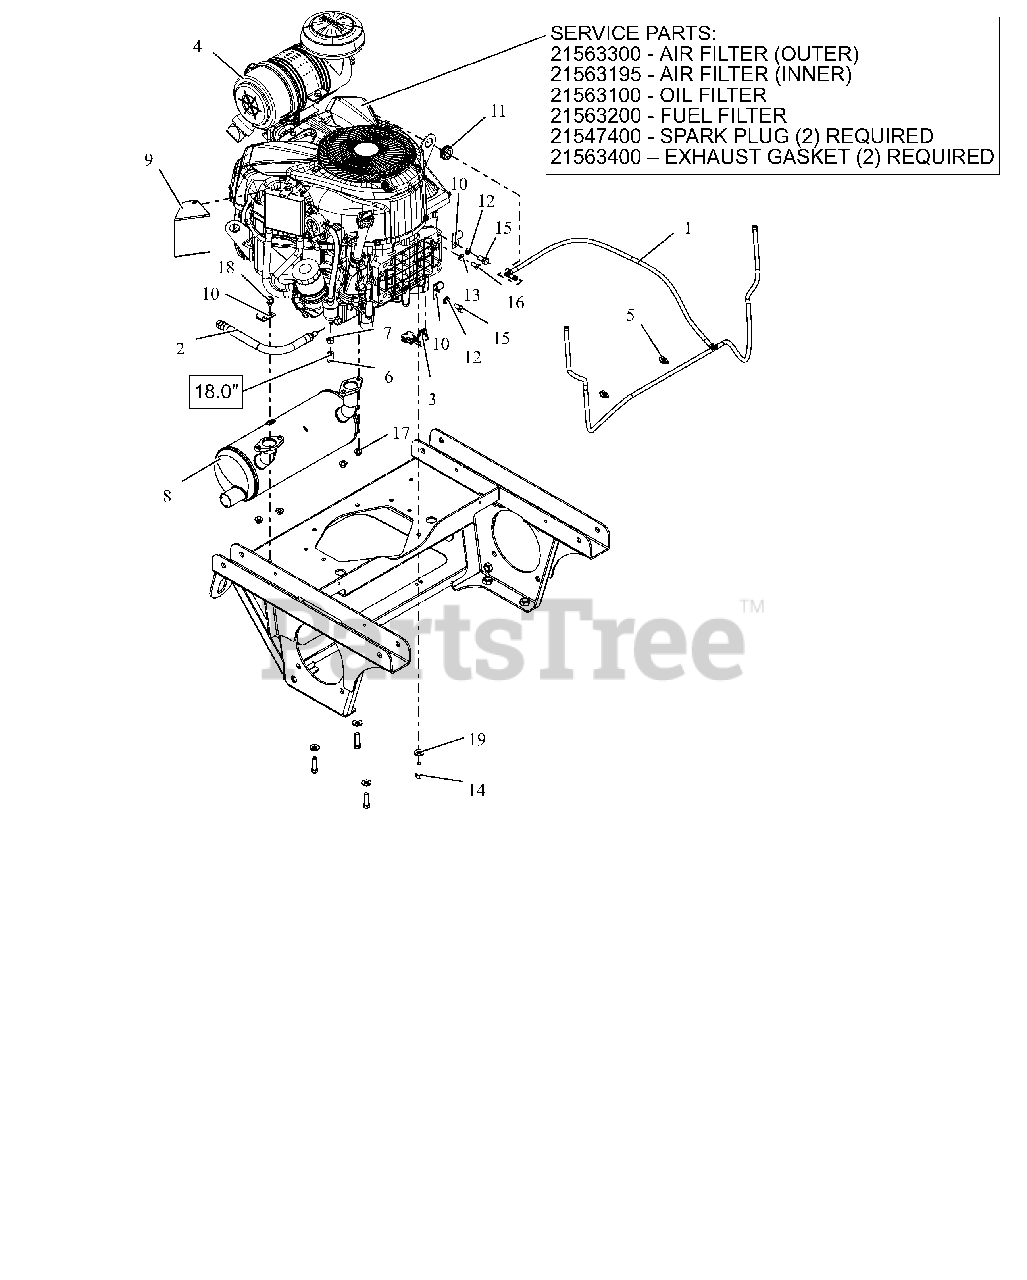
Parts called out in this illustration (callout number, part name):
1	ASM, VAPOR LINE
2	HOSE, OIL DRAIN
3	HARNESS, YAMAHA CARB ADAPTER
4	ENGINE, YAMAHA MX 825V
4	AIR FILTER (OUTER) - YAMAHA
4	AIR FILTER (INNER) - YAMAHA
4	FILTER, OIL - YAMAHA 824
4	FILTER-FUEL YAMAHA 824
4	PLUG, SPARK
4	GASKET, MUFFLER YAMAHA 824
5	ROUTING CLIP (1/2" ID)
6	HOSE, .25 LOW-PERM BULK GAS
7	CLAMP, FUEL LINE
8	MUFFLER, YAMAHA
9	DEFLECTOR,YAMAH OIL COOLER AIR
11	GROMMET,RUBBER.688 IDX1.000 OD
12	WSHR,LK-REG .375X.094 ZCC
13	WSHR,LK-REG .312X.078 ZCC
14	BLT, HEX .38-16X1.25 G5 ZCC NT
15	BLT,HEX .38-16X.75 G5 ZCC
16	BLT,HEX .31-18X.75 G5 ZCC
17	NUT-LK-TOP-FLG M8 ZCC
18	SCR,TAP .375-16X.50 HWH TR ZCC
19	WASHER, 3/8" SPRING DISC
